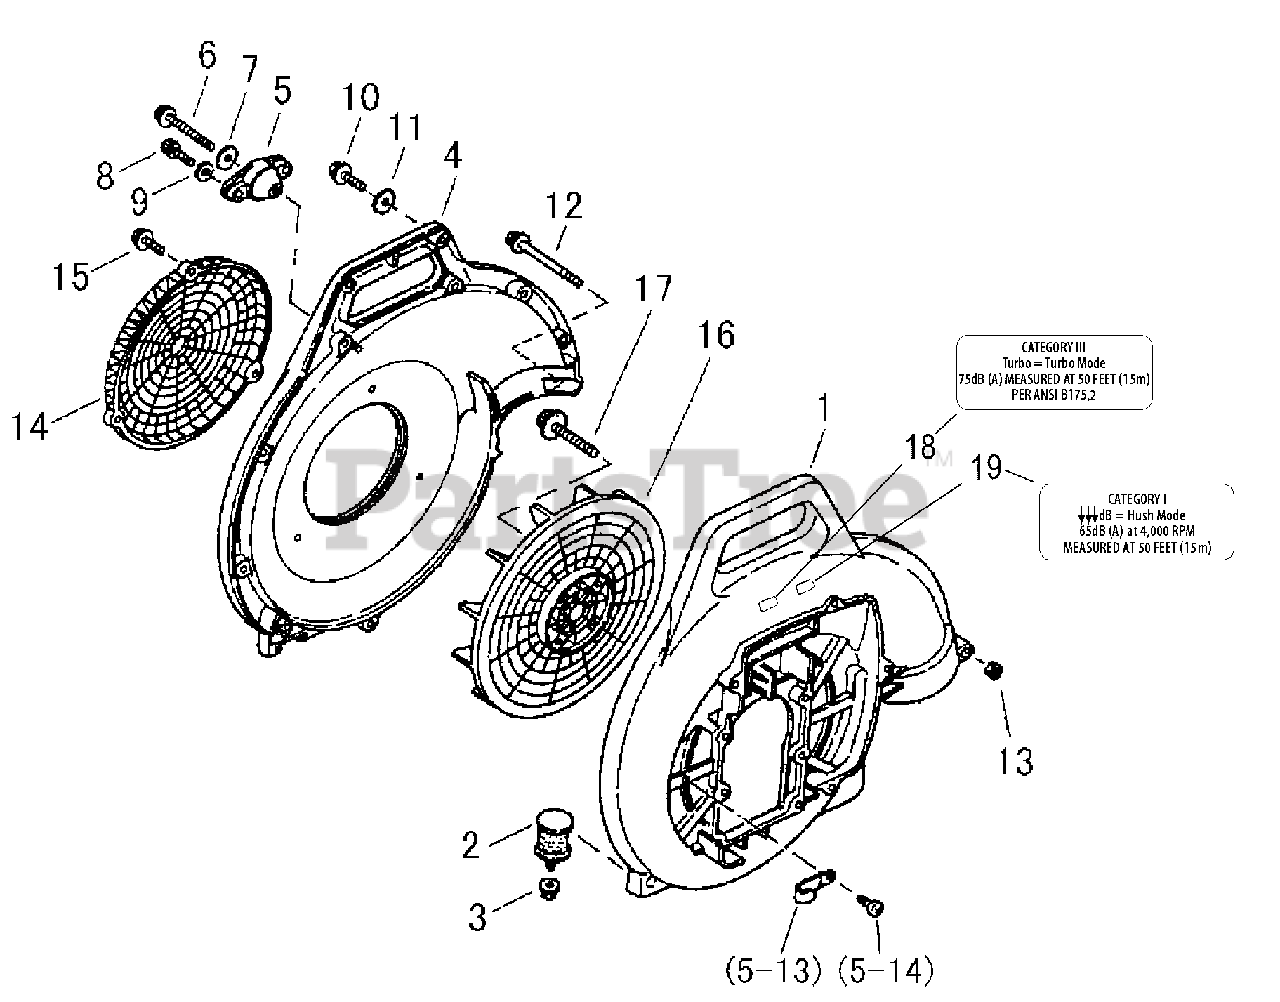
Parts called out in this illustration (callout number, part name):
1	CASE, VOLUTE
2	CUSHION, AV 6
3	NUT, FLANGE M6
4	COVER, FAN
5	CUSHION, AV 5
6	BOLT TAPPING M5
7	WASHER Ø25ר5.5×2
8	BOLT M5×16
9	WASHER Ø15ר5.2×1.6
10	BOLT M5×20
11	WASHER, FLAT 5.5×10×0.8
12	BOLT M5×70
13	NUT M5
14	COVER, INTAKE
15	BOLT, TAPPING
16	FAN
17	BOLT M6×40
18	LABEL, NOISE
19	LABEL, NOISE
